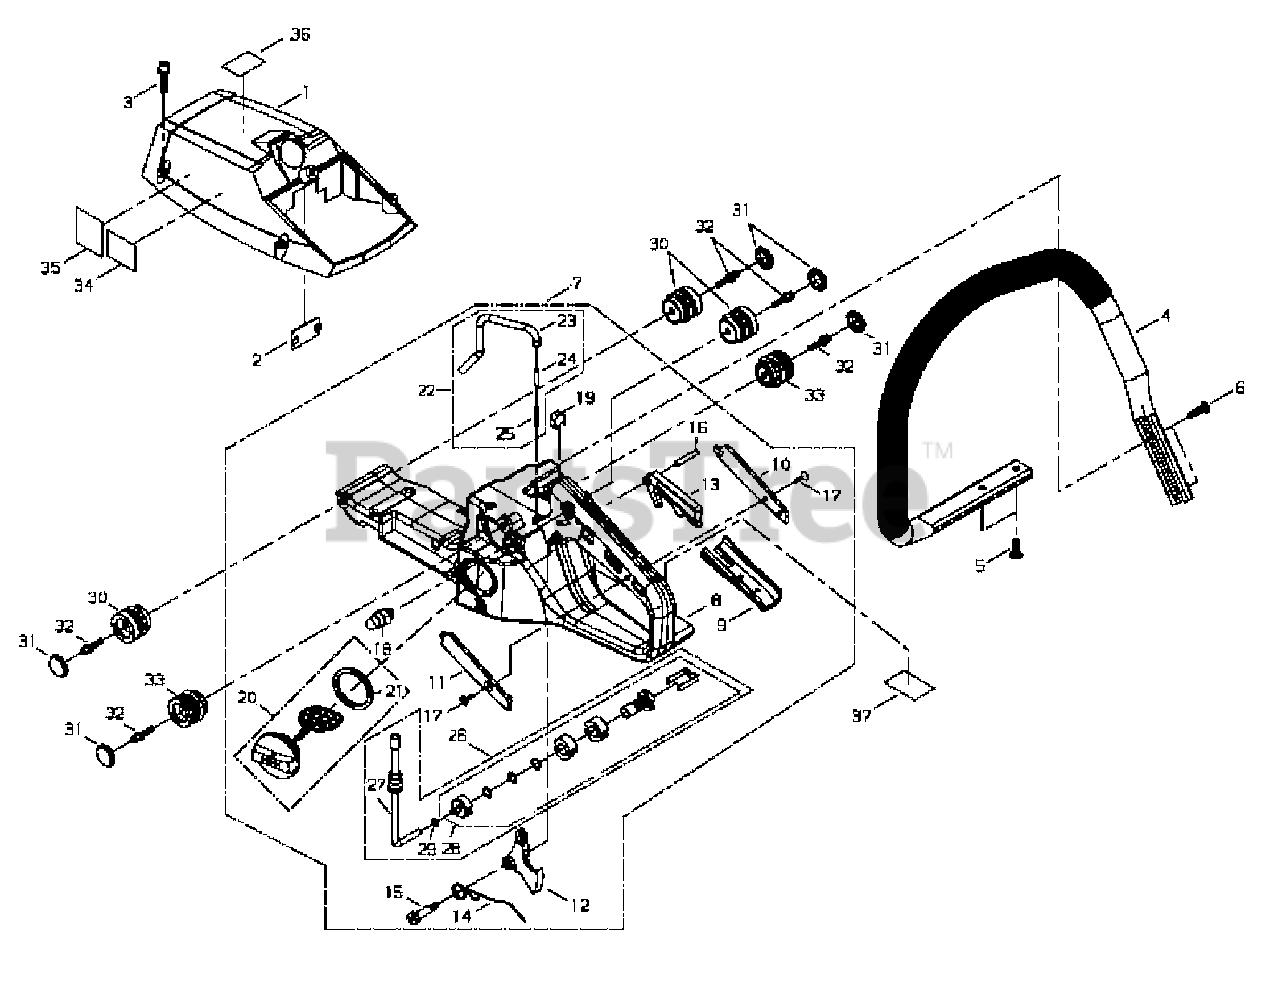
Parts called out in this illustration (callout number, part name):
1	COVER, ENGINE
2	PLUG
3	BOLT 5
4	HANDLE, FRONT
5	SCREW M5
6	SCREW 5×20
7	HANDLE ASSY, REAR
8	HANDLE, REAR
9	GRIP
10	PLATE R
11	PLATE L
12	LEVER, THROTTLE
13	LEVER, LOCK
14	SPRING, RETURN
15	BOLT
16	PIN, SPRING Ø4×25 MM
17	SCREW
18	LOCKOUT, THROTTLE
19	STOPPER
20	CAP ASSY, FUEL
21	GASKET, CAP
22	BREATHER
23	PIPE, VENT
24	ELEMENT
25	SPRING
26	PIPE ASSY, FUEL
27	PIPE, FUEL
28	FILTER, FUEL
29	CLIP Ø6
30	CUSHION
31	PLUG
32	BOLT 5
33	CUSHION
34	LABEL, CAUTION K
35	LABEL, CAUTION A
36	LABEL, CAUTION
37	LABEL, CAUTION H
